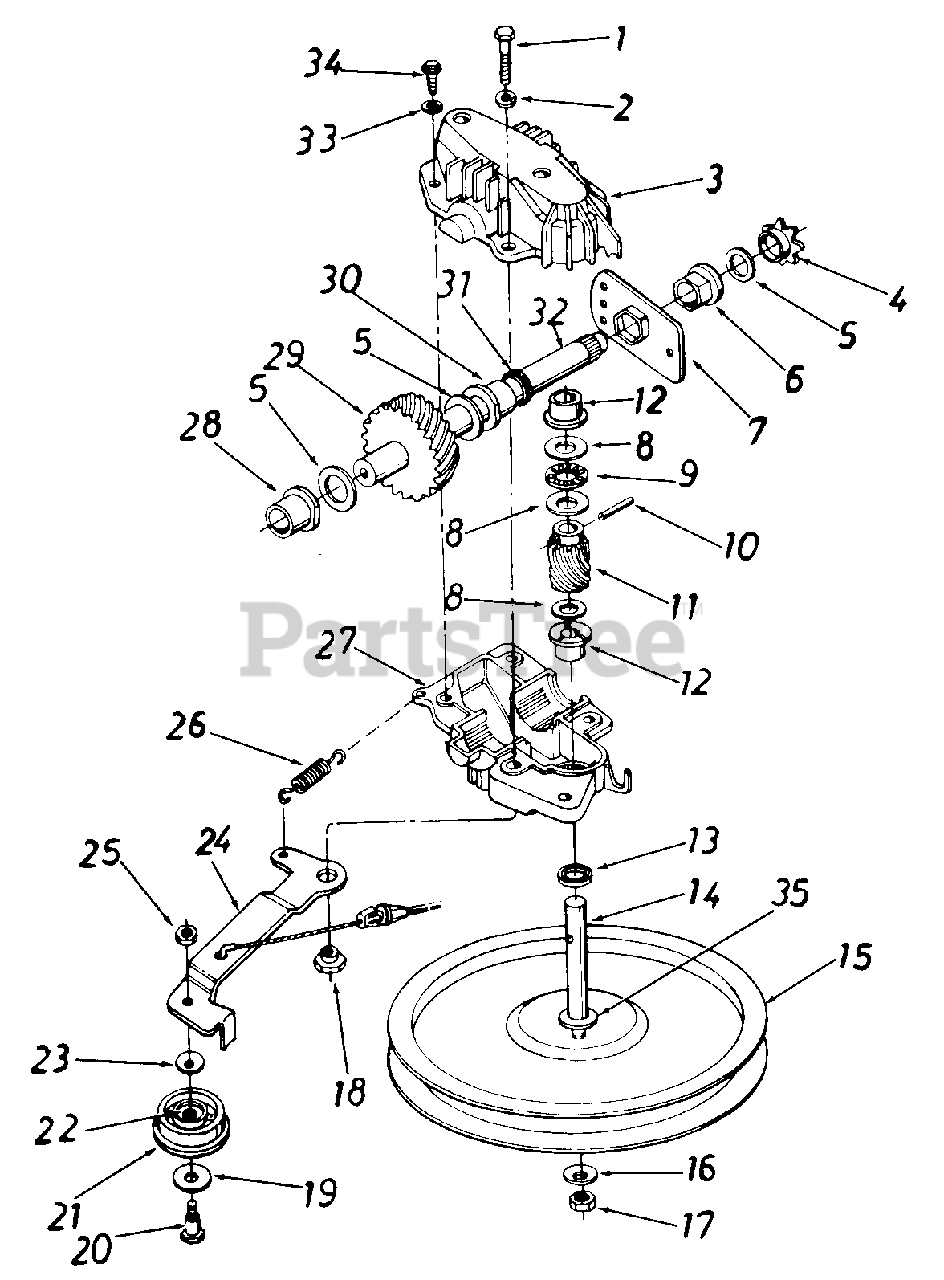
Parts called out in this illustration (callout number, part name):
1	Hex Bolt 1/4-20 x 1.25" Lg.*
2	L-Wash. 1/4" I.D.*
3	Upper Hsg. Half
4	#48 Sprocket 7 Tooth x 1/2 Pitch
5	Fl-Wash. 5/8" I.D. x .030
6	Hex Flange Brg. .631" I.D.
8	Thrust Wash. .382" I.D. x .70" O.D.
9	Thrust Bearing .375" I.D. x .812" O.D.
10	Spring Pin Spir. 1/8" x .62" Heavy
11	11 Tooth Helical Gear
12	Flange Bearing
13	Oil Seal
14	Pulley-Transmission Shaft
15	Fl-Pulley 5.06" O.D.
16	Bell-Wash. .265" I.D. x 75"
17	Hex L-Nut 1/4-28 L.H. Thd.
18	Shld. Spacer .375" Dia. x .170
19	Fl-Wash. .390" I.D. x 1.0"
20	Shld. Bolt .375" Dia. x .40"
21	Fl-Idler Plastic 1.50" Dia
22	Needle Brg. .375" x .31
23	Bell-Wash. .265" I.D. x 75"
24	Idler Brk't. Ass'y.
25	Hex Patch L-Nut 1/4-28 Thd.
26	Extension Spring 1.12" Lg.
27	Lower Hsg. Half
28	Flange Bearing .566 Dia.
29	33 Tooth Helical Gear
30	Flange Bearing .629 Dia.
31	Oil Seal .625 Dia.
32	Gear Sprocket Shaft
33	L-Wash. #10 I.D.
34	Hex B-Tap Scr. #10 x .62"
35	Hex Washer .26" x .88"
